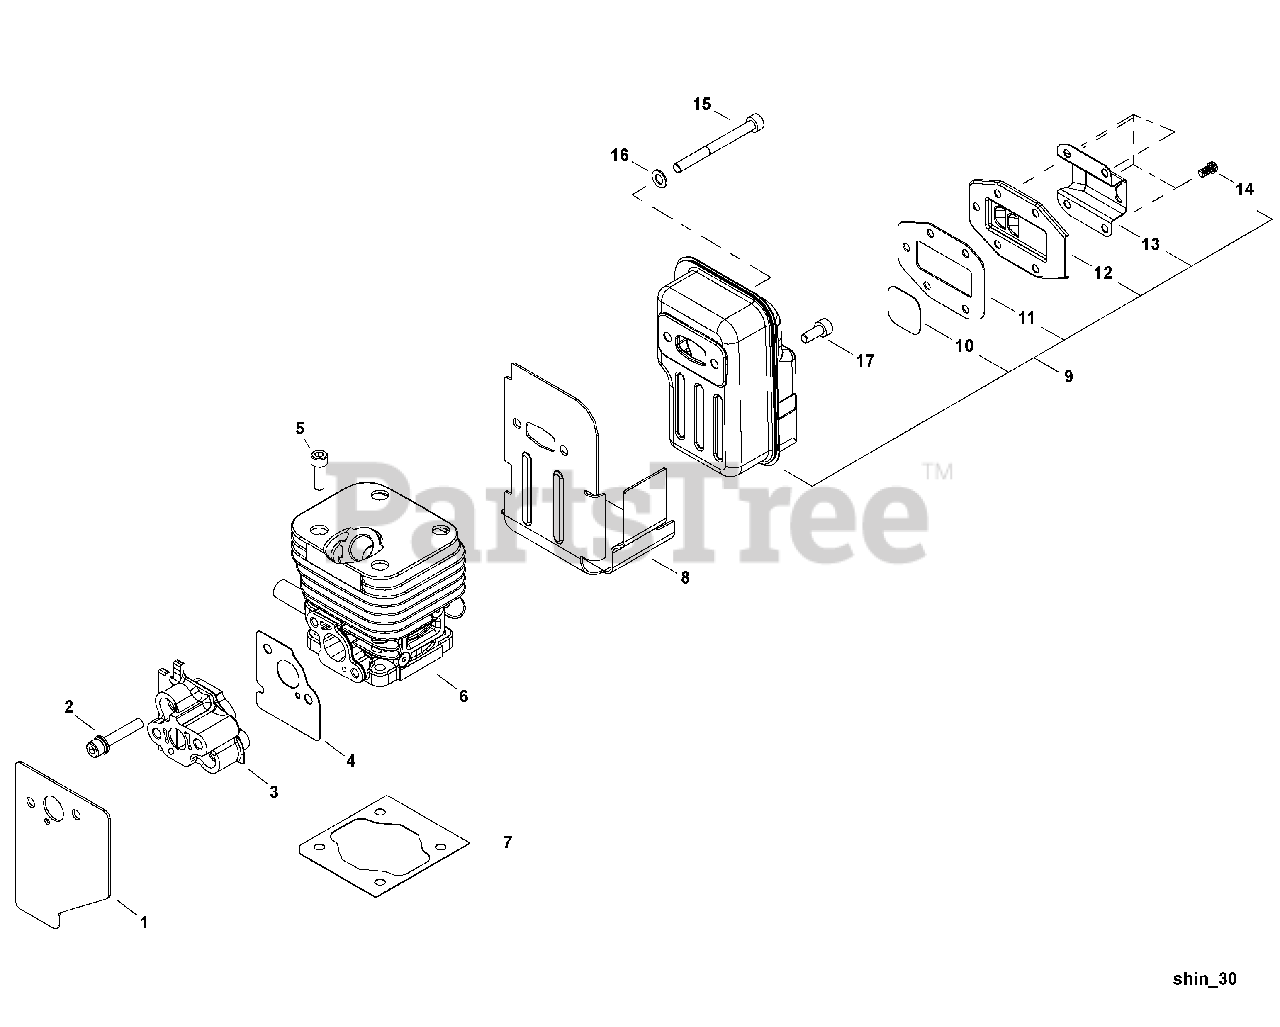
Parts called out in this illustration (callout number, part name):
1	GASKET, INTAKE
2	SCREW - 5X30
3	INSULATOR
4	GASKET, INTAKE
5	SCREW - 5X16
6	CYLINDER
7	GASKET, CYLINDER
8	DEFLECTOR, HEAT
9	MUFFLER ASSY
10	SCREEN, SPARK ARRESTOR
11	GASKET, EXHAUST
12	GUIDE, EXHAUST - INNER
13	GUIDE, EXHAUST - OUTER
14	SCREW - 4X8
15	SCREW - 5X55
16	WASHER - 5
17	SCREW - 5X12
